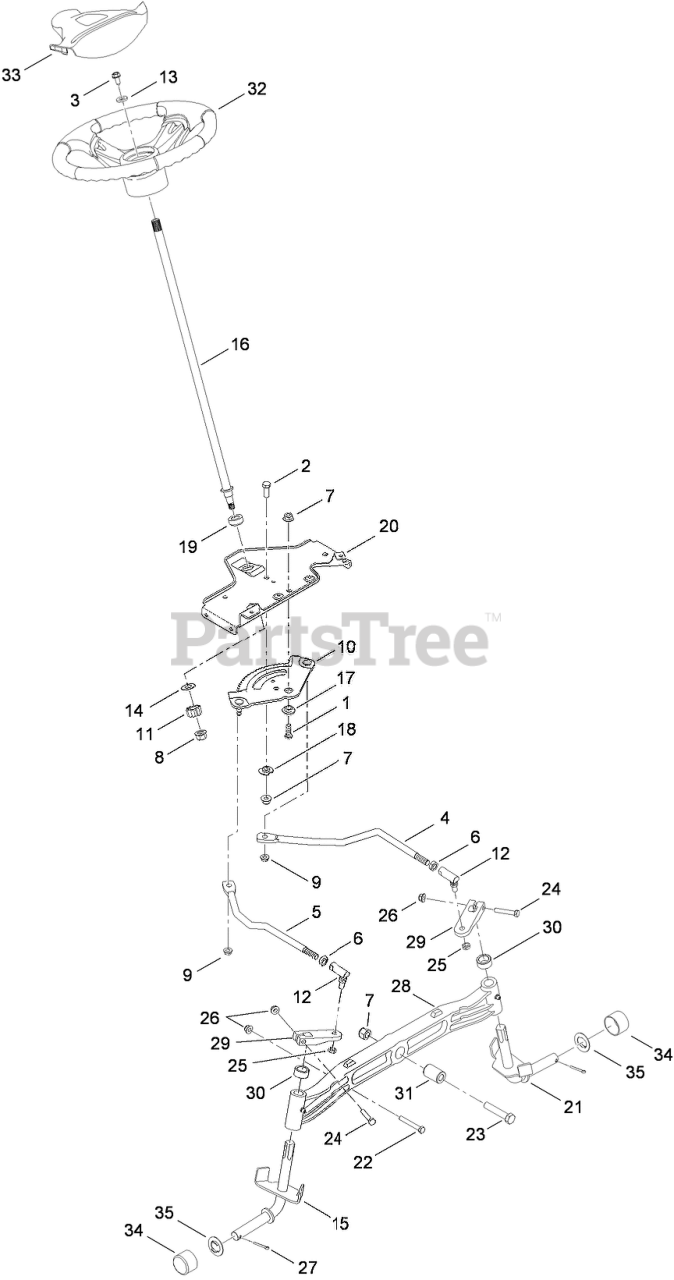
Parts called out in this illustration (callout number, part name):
1	SCREW-HH
2	SCREW-HH
3	SCREW-HH
4	LINK-DRAG, LH
5	LINK-DRAG, RH
6	NUT-JAM
7	NUT-LOCK, FLANGE
8	NUT-LOCK, FLANGE
9	NUT-LOCK, FLANGE
10	GEAR-STEERING
11	GEAR-PINION, STEERING
12	BALL JOINT ASM
13	WASHER-FLAT
14	WASHER-FLAT
15	RH AXLE ASM
16	SHAFT-STEERING
17	SPACER-SHOULDER
18	SPACER
19	BEARING-FLANGE, HEX
20	BRACKET-SUPPORT, STEERING
21	LH AXLE ASM
22	SCREW-HH
23	SCREW-HH
24	BOLT-HH
25	NUT-HEX, LOCK
26	NUT-LOCK, FLANGE
27	PIN-COTTER
28	AXLE-CAST
29	BLOCK-STEERING
30	SPACER
31	SPACER
32	WHEEL-STEERING, SOFTGRIP
33	COVER-WHEEL, STEERING
34	CAP-BUMPER
35	WASHER-FLAT
